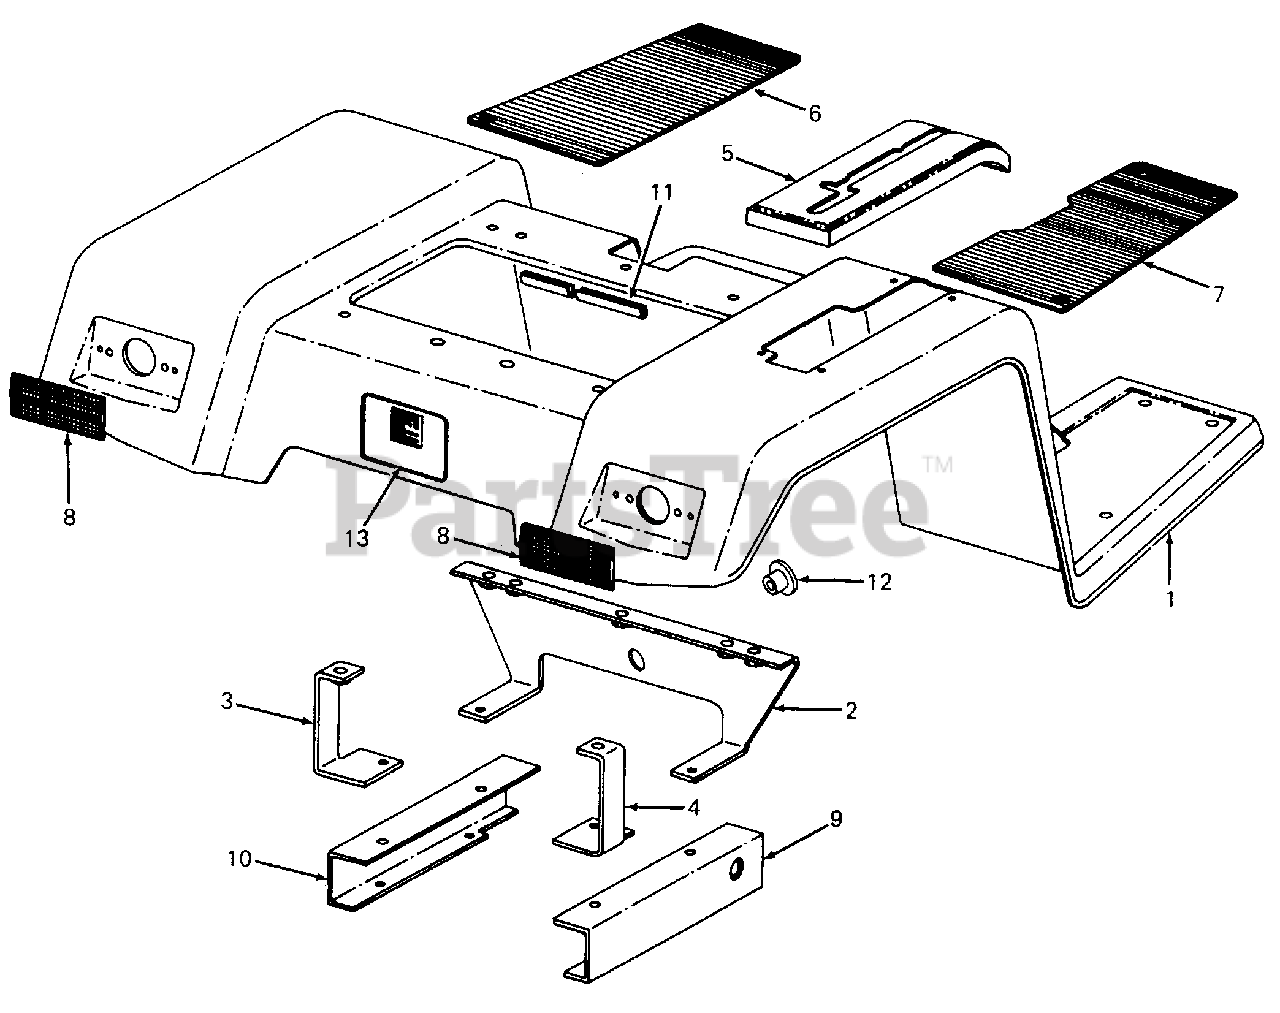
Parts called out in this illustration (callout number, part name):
1	Fender w/Hole
2	Support, Fender Front
3	Support, Fender Rear LH
4	Support, Fender Rear RH
5	Cover, Shift
6	Tread, Platform LH
7	Tread, Platform RH
8	Reflector
9	Support, Fender LH
10	Support, Fender RH
11	Strip, Trim -39.38 in. Long
12	Bushing, Snap
13	Kit, Chassis Label
